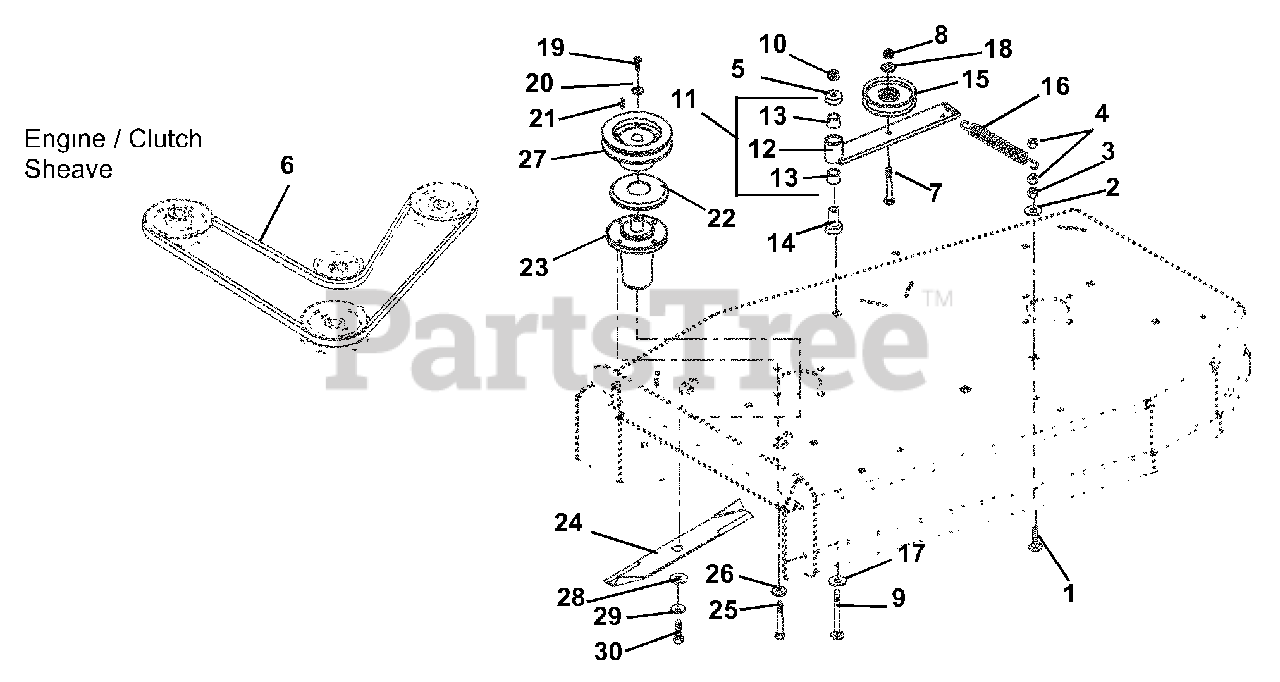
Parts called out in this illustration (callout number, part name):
1	@BLT-RDHDSQNK .38-16X1.50 G5YZ
2	@WSHR-LK .38X.094 REG YWZC
3	@NUT-HEX .38-16 YWZC
4	@NUT-LK-CTR .38-16 YWZC
5	WSHR-FL-STL .515X1.625X.250 YZ
6	V-BELT, HB-WRAPPED
7	@BLT-RDHDSQNK .38-16X2.75 G5YZ
8	@NUT-LK-CTR .38-16 YWZC
9	@BLT-RDHDSQNK .50-13X3.75 G5YZ
10	@NUT-LK-CTR .50-13 YWZC
11	ASSEMBLY - IDLER PIVOT ARM
12	WMT - IDLER PIVOT ARM
13	BRG, 1.00 X 1.12 X .75
14	BEARING, PEDESTAL
15	IDLER-FLAT 4.00X.38 (2.00 W)
16	SPRING, EXTENSION
17	WSHR-FL-STL.755X1.375X.062YWZC
18	WSHR-FL-STL .375X1.125X.065YWZ
19	BLT-HEX .38-16X1.00 YZ GR8
20	WASHER, CUPPED SERRATED, .375
21	KEY, SQ .25X.25X1.00 RC 40-50
22	SLINGER, DUST
23	ASM,MAINT FREE SPINDLE
24	BLADE, 32" (16.25)
24	BLADE, 36" SAND, TUNGSTEN
25	@BLT-HEX .38-16X1.00 GR5 YWZC
26	@WSHR-LK .38X.094 REG YWZC
27	WELDMENT, SPINDLE SHEAVE 5.00
28	WSHR-FLT .640X1.75X.250 YWZC
29	WSHR-BLVL .669X1.535X.138
30	BLT-HEX .62-18X1.75 GR8 YWZC
